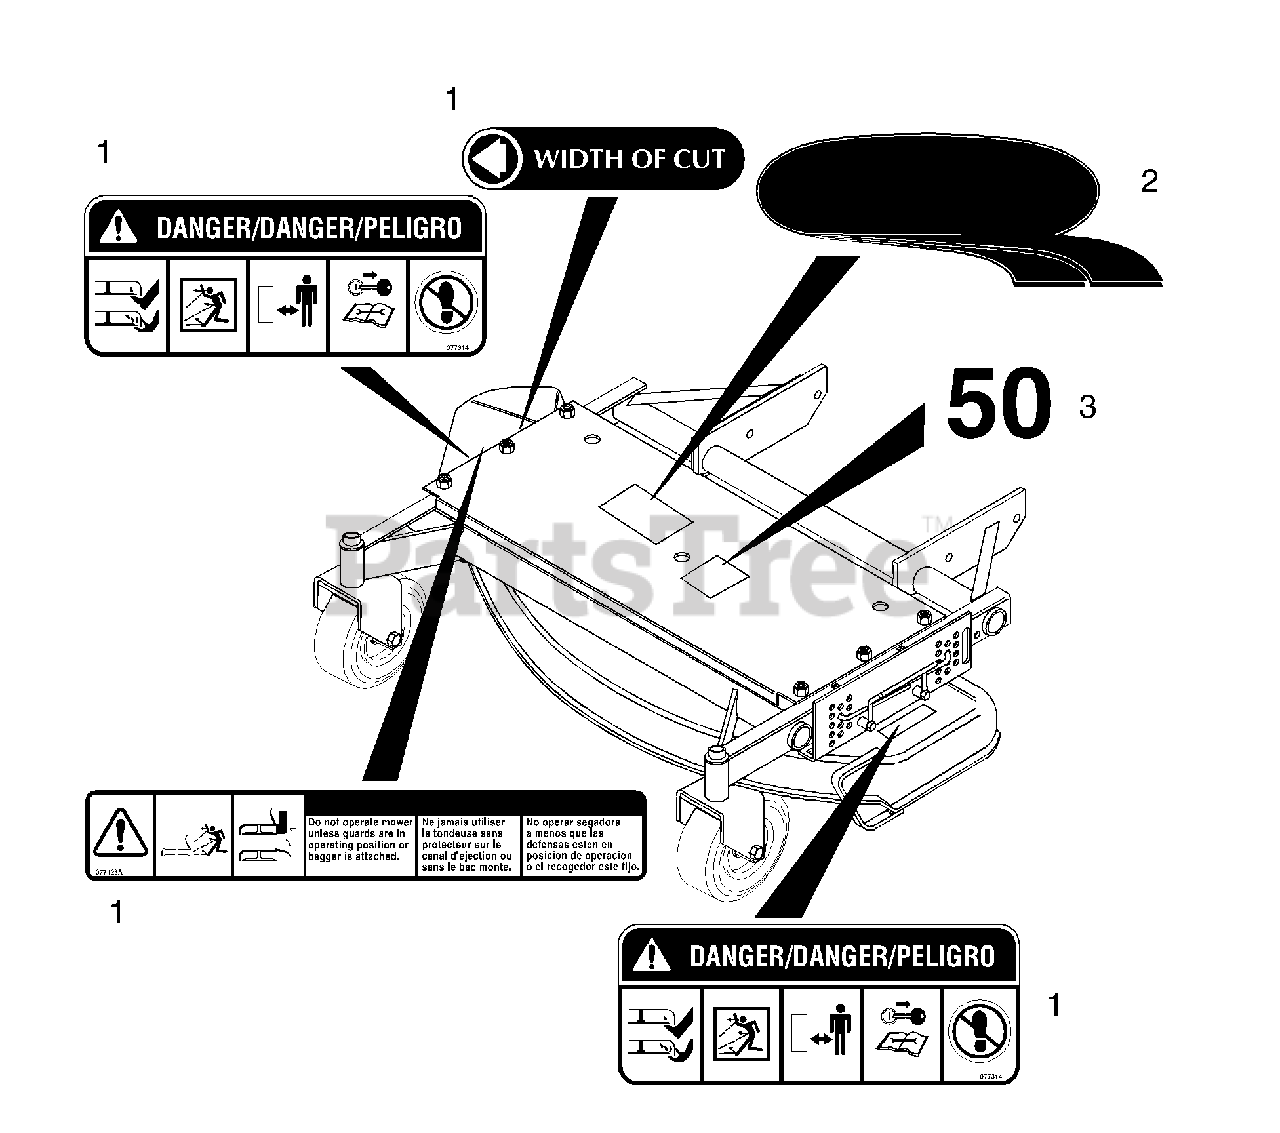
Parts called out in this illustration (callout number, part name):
1	Decal Set
2	Decal-Gravely Logo RH
3	Decal-50"
